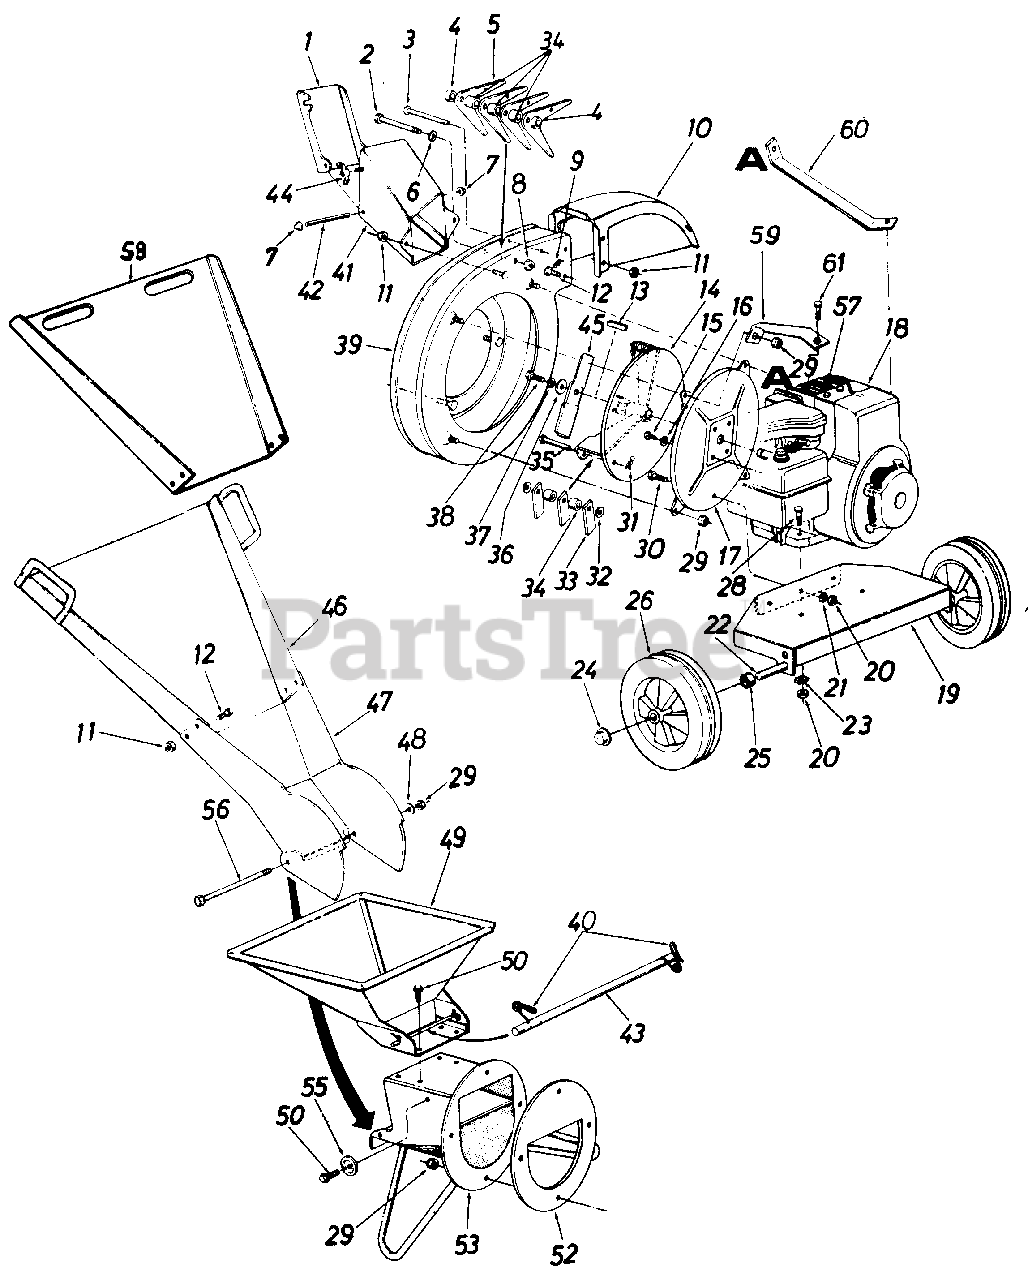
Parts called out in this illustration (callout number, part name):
1	Door Chip It
2	Hex Bolt 1/2-20 x 4.50" Lg.
3	Clevis Pin
4	Flail Spacer 7/32" Lg.
5	Cutting Finger
6	L.-Wash. 1/2" I.D.
7	Palnut 3/16" Dia.
8	Hex Jam Nut 1/2-20 Thd.
9	Cotter Pin 3/32" Dia. x 3/4"
10	Chute Delfector
11	L.-Nut 1/4-20 Thd.
12	Hex Bolt 1/4-20 x .50" Lg.
13	Sq. Key 1/4" x 2.00" Lg.
14	Impeller Assembly
15	Hex Bolt 5/16-24 x 3/4" Lg.
16	L.-Wash. 5/16" I.D.4
17	Hopper to Engine Mtg. Plate
18	Engine
19	Engine Mounting Plate
20	Hex Nut 5/16-24 Thd.
21	L.-Wash. 5/16" I.D.
22	Shaft
23	Special L.-Wash. 5/16" I.D.
24	Push Cap
25	Spacer
26	Wheel Ass'y.-Comp.
28	Hex Bolt 5/16-24 x 1.50" Lg.
29	Elastic Lock Nut 5/16-18 Thd.
30	Hex Bolt 5/16-24 x .62" Lg.
31	Cotter Pin 1/8" Dia. x 1.00" Lg.
32	Fl.-Wash. .531" I.D. x .937 O.D. x .09
33	Flail
34	Spacer 23/32" Lg.
35	Clevis Pin .50" Dia. x 3.0" Lg.
36	Fl.-Wash. .406" I.D. x 1.25" O.D. Hdn.
37	L.-Wash. 3/8" I.D. H.D.
38	Hex Bolt 3/8-24 x 2.0" Lg. H.T.
41	Chlp lt Guide Ass'y.
42	Hinge Pin
43	Release Bar
44	Wing Nut Elastic 1/4-20 Thd.
47	Lower Leaf Ramp Section
48	Fl.-Wash. 5/16" I.D.
49	Hopper Assembly
50	Hex Wash. Hd. Self-Tap Scr. 5/16-18 x .75" Lg.
52	Back-Up Plate
53	Inlet Guide Assembly
55	Stop Washer
56	Hex Bolt 5/16-28 x 8.38" 4.
57	Spark Plug Boot
60	Impeller Hsg. Support Brace -L.H.
61	Part of Engine
